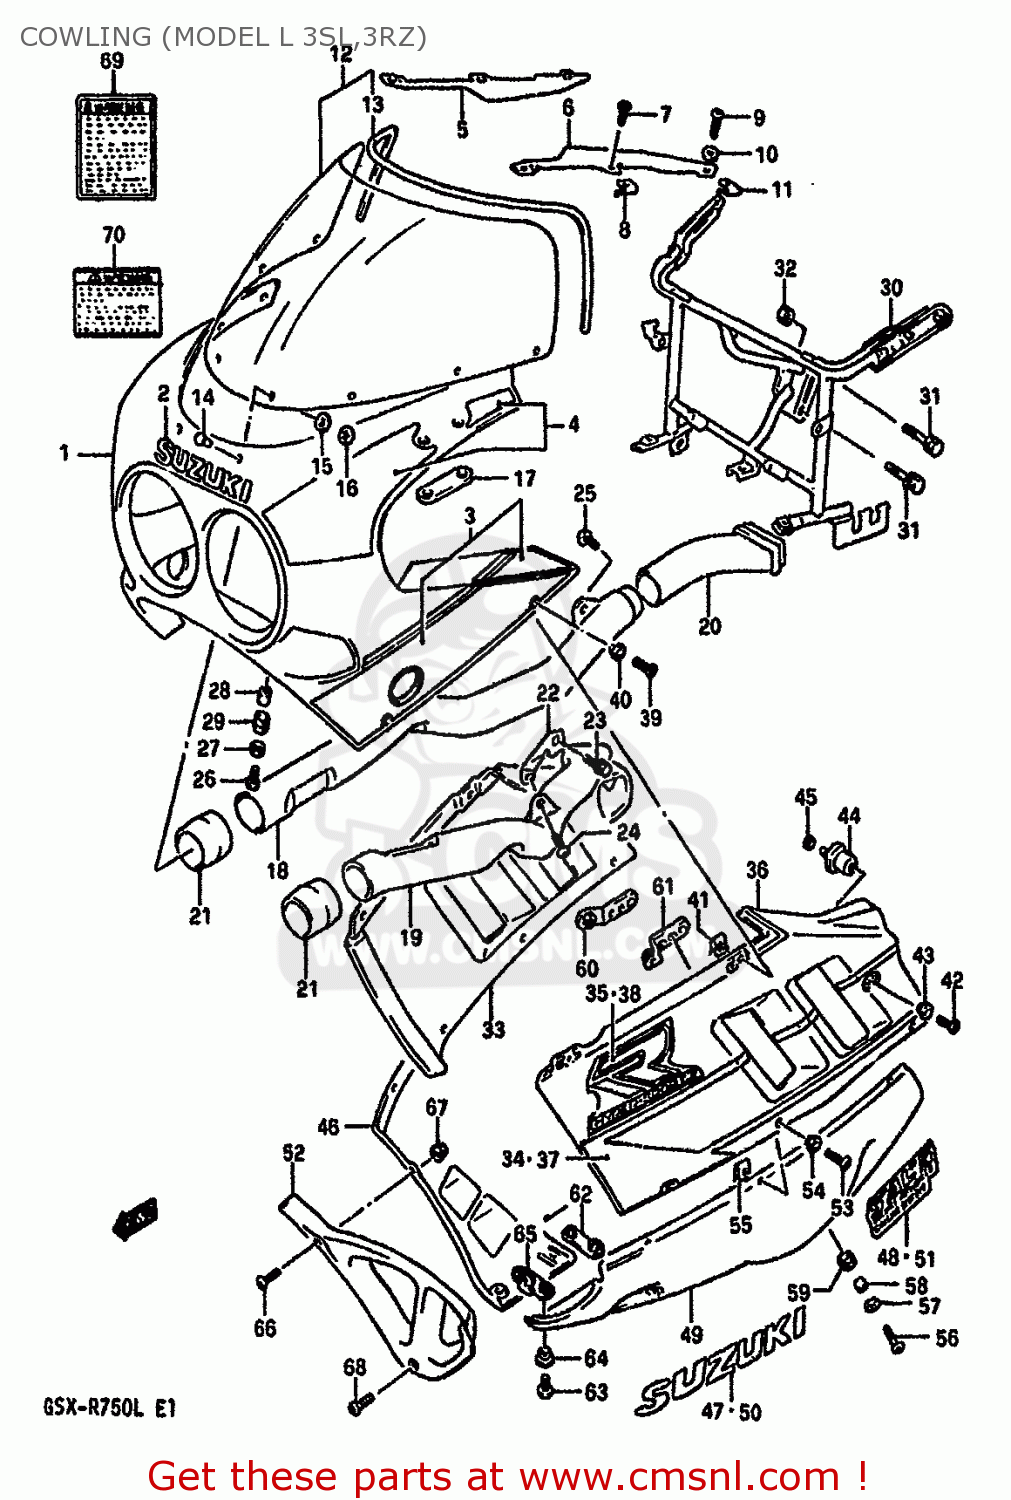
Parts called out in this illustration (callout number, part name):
1	BODY ASSEMBLY,COWLING
2	EMBLEM,FR
3	TAPE SET,COWLING,UPPER
4	TAPE SET
5	PANEL,COWLING UPR,R
6	PANEL,COWLING UPR,L
7	SCREW(5X10)
8	NUT
9	SCREW(5X14)
10	WASHER(5.2X11X1)
11	NUT
12	WINDSCREEN
13	MOLDING
14	PIN,WINDSCREEN
15	CUSHION
16	NUT
17	CUSHION,RR VIEW MIRRORR
18	PIPE,AIR INTAKE,FRONT
19	PIPE,AIR INTAKE,FRONT
20	PIPE,AIR INTAKE RR,R
21	JOINT,AIR INTAKE
22	PLATE,AIR INTAKE,LEFT
23	BOLT
24	SCREW 6X12
25	SCREW
26	SCREW(6X20)
27	WASHER(6.5X18X1)
28	SPACER
29	CUSHION
30	BRACE,COWLING
31	BOLT
32	NUT ,8MM
33	COVER,COWLING SIDE,RIGHT
34	TAPE SET,COWLING SIDE
35	EMBLEM,COWLING SIDE
36	COVER,COWLING SIDE,LEFT
37	TAPE SET,COWLING SIDE
38	EMBLEM,COWLING SIDE
39	SCREW(5X18)
40	WASHER(5.2X14X1.5)
41	NUT,HEADLAMP HOUSING,UPPER
42	SCREW(6X12)
43	WASHER(6.3X16X1.5)
44	CUSHION,COWLING
45	WASHER,LOCK
46	COWLING,UNDER RH (BLUE/BLUE)
47	EMBLEM
48	EMBELEM,SACS
49	COWLING,UNDER
50	EMBLEM,COWLING UNDER,L
51	EMBELEM,SACS
52	COWLING,UNDER,CENTER
53	SCREW(5X18)
54	WASHER(5.2X14X1.5)
55	NUT,HEADLAMP HOUSING,UPPER
56	SCREW(6X20)
57	WASHER(6.5X18X1)
58	SPACER
59	CUSHION
60	BRACKET
61	BRACE,COWLING UNDER,LH
62	BRACE,COWLING LWR COVER RR
63	SCREW(6X16)
64	WASHER(6.3X16X1.5)
65	BRACE,COWLING LWR COVER
66	SCREW(5X14)
67	NUT
68	SCREW(6X16)
69	LABEL (WARNING SCREEN)
70	LABEL, WARNING SAFETY
